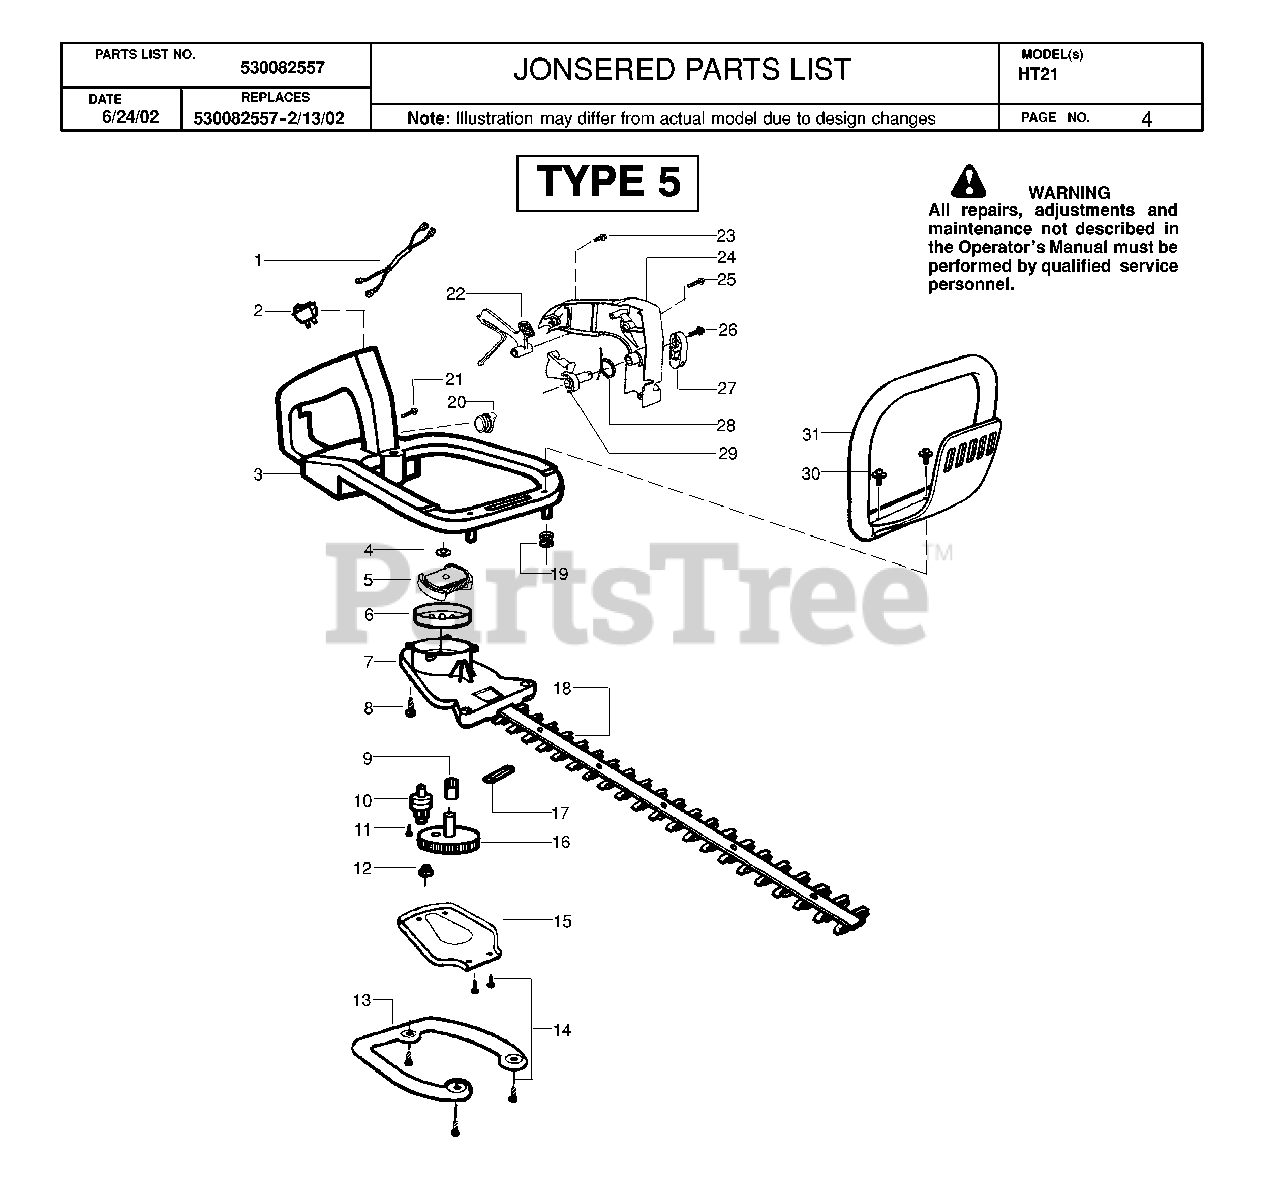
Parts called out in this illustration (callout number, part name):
3	ASSY-REAR HANDLE & TANK
4	WASHER FLAT
6	CLUTCH DRUM
7	GEARBOX ASSY
8	SCREW-10-14 X 13/16 (PL
11	SCREW-10-16 X 1/2, TYPE 2
12	BLADE BUSHING
13	ISOLATOR PLATE
15	PLATE-GEARBOX COVER
18	BLADE ASSEMBLY
19	ANTIVIBE MOUNT
20	COVER
21	SCREW-10-16 X 1-3/8 PLA
22	LOCKOUT-THROTTLE
26	SCREW 8-16 X 9/16 (PLAS
